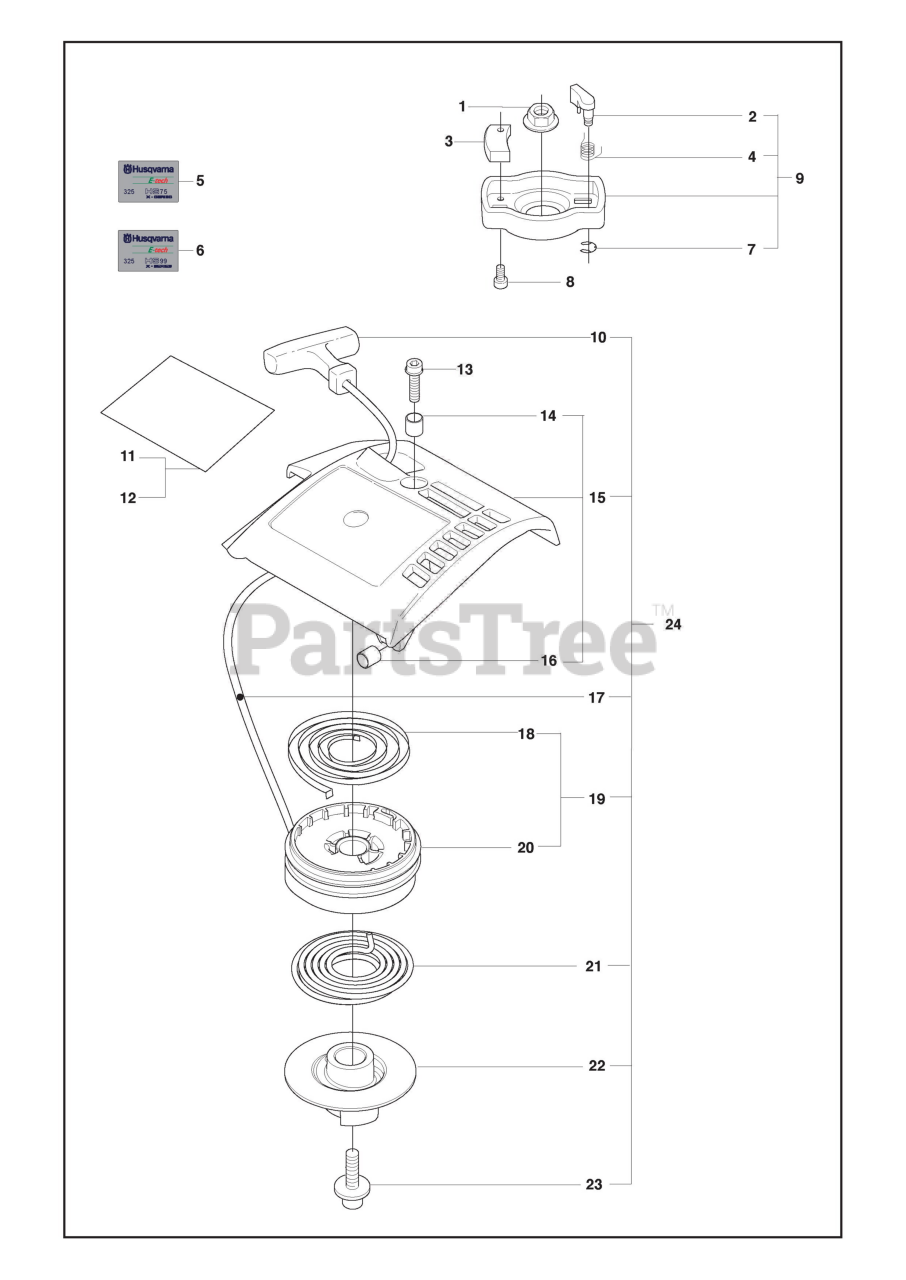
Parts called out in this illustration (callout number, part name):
1	FLANGE NUT
2	STARTER PAWL
9	STARTER HANDLE
13	SPACING SLEEVE
14	COUNTERWEIGHT
15	STARTER HOUSING
16	SPACING SLEEVE
17	STARTER ROPE
19	STARTER PULLEY
20	STARTER PULLEY
21	SPRING - DRIVER
22	DRIVER PULLEY
24	RP STARTER ASSY
